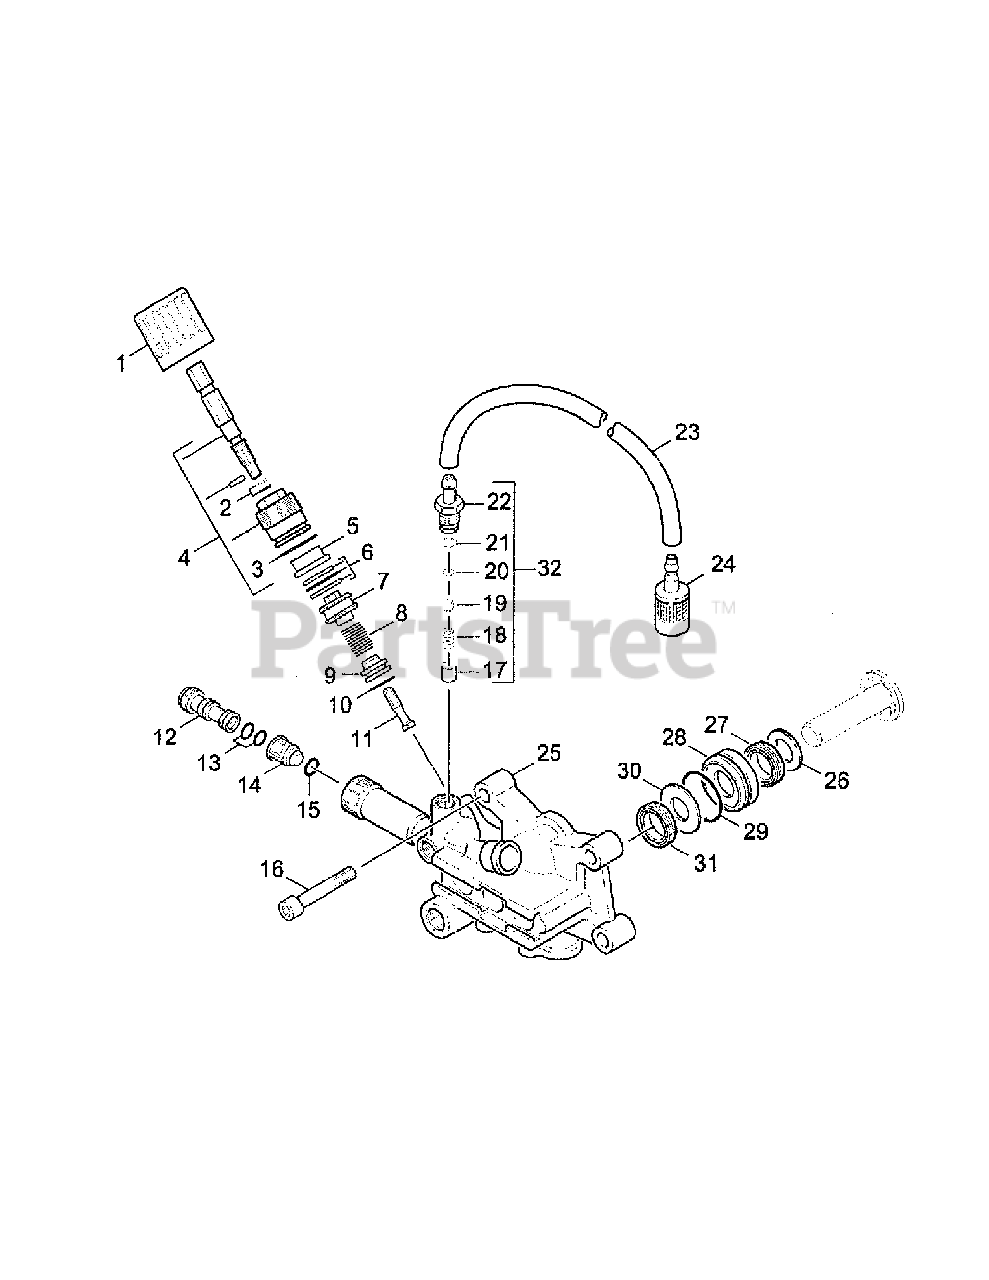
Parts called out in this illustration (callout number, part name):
1	Handle
2	Gasket
3	Gasket
4	Screw Union
5	Sleeve
6	Gasket
7	Piston
8	Helical Spring
9	Valve Seat
10	Gasket
11	Screw
12	Nozzle Insert
13	Gasket
14	Valve Pin
15	Gasket
16	Screw
17	Sleeve
18	Helical Spring
19	Ball
21	Gasket
22	Nipple
23	Hose
24	Filter
25	Cylinder Head
26	Washer
27	Grooved Ring
28	Bushing
29	Gasket
30	Washer
31	Seal
32	Rebuild Kit
